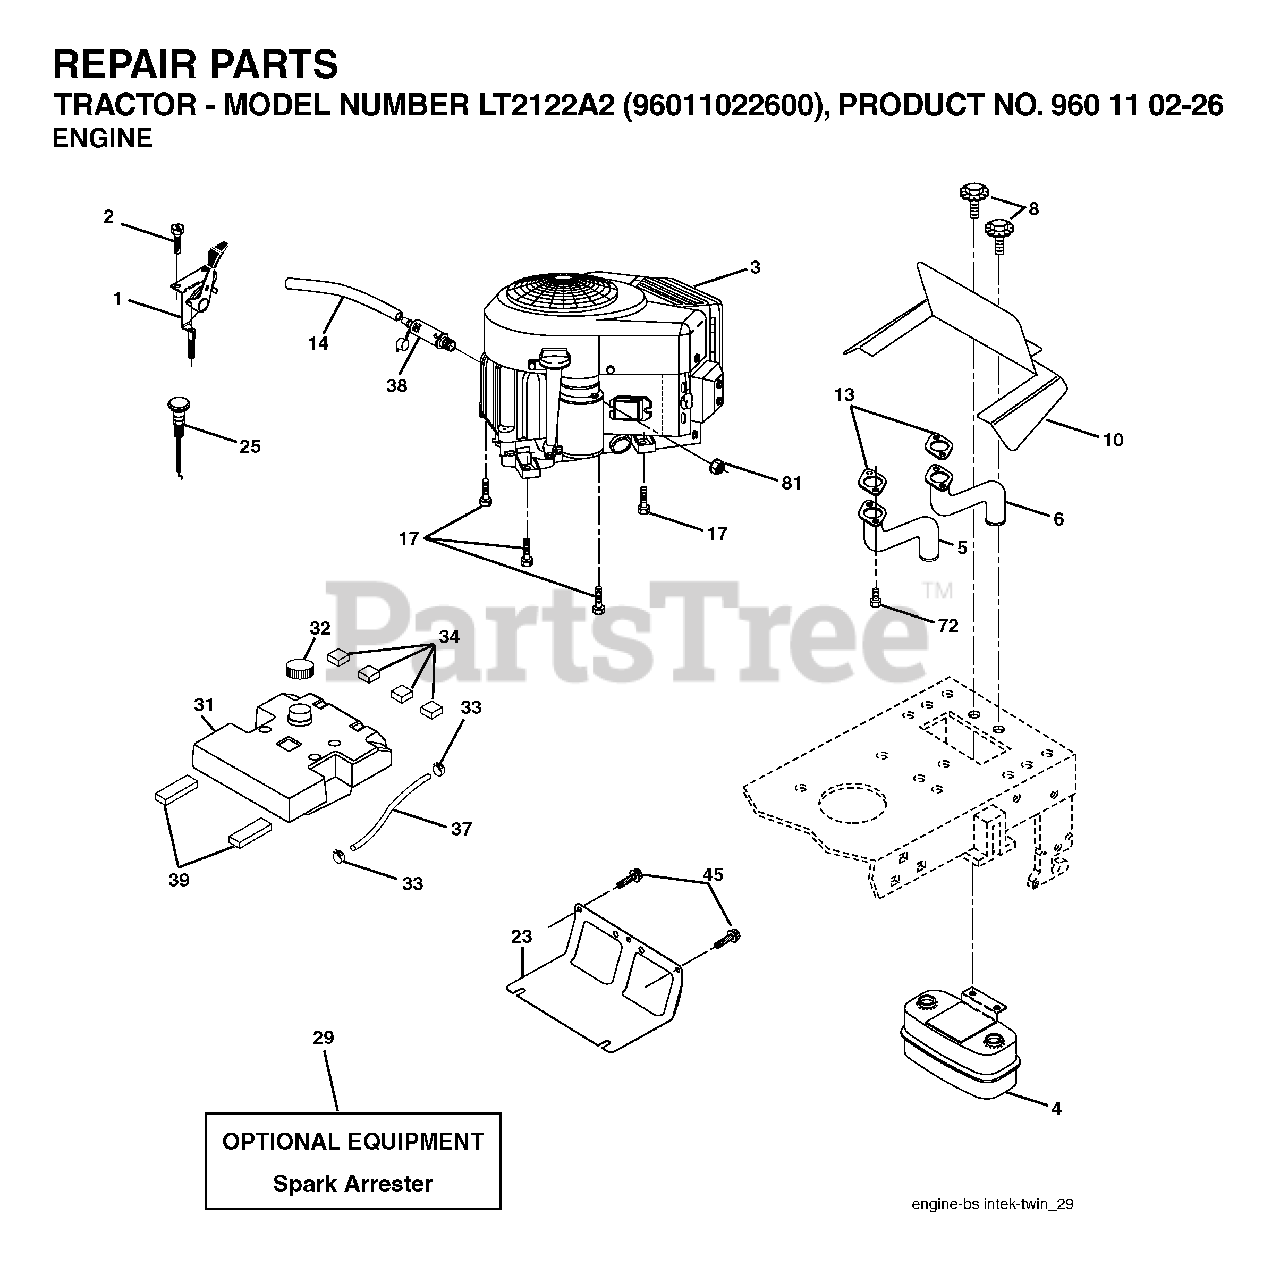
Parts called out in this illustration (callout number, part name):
1	THROTTLE CABLE
2	SCREW
4	MUFFLER.TWIN.CYL.LOW.TONE
5	TUBE MANIFOLD LH
6	EXHAUST TUBE RH
8	BOLT, 5/16-18 X 1 3/4
10	SHIELD.BROWNING.B&S
13	GASKET.MUFFLER
14	TUBE, DRAIN OIL ASM.
23	SHEILD.BROWNING.DBR.GUARD
25	CONTROL CHOKE
29	ARRESTER SPARK (OPTIONAL)
31	TANK.FUEL(3.5.GAL)
32	FUEL CAP
33	HOSE CLAMP
34	PAD-SPACER LT
38	PLUG DRAIN OIL EASY
39	PAD IDLER TI
45	SCREW, 3/8-16X3/4
72	SCREW.SOCKET.HEAD.5/16-18
81	NUT
